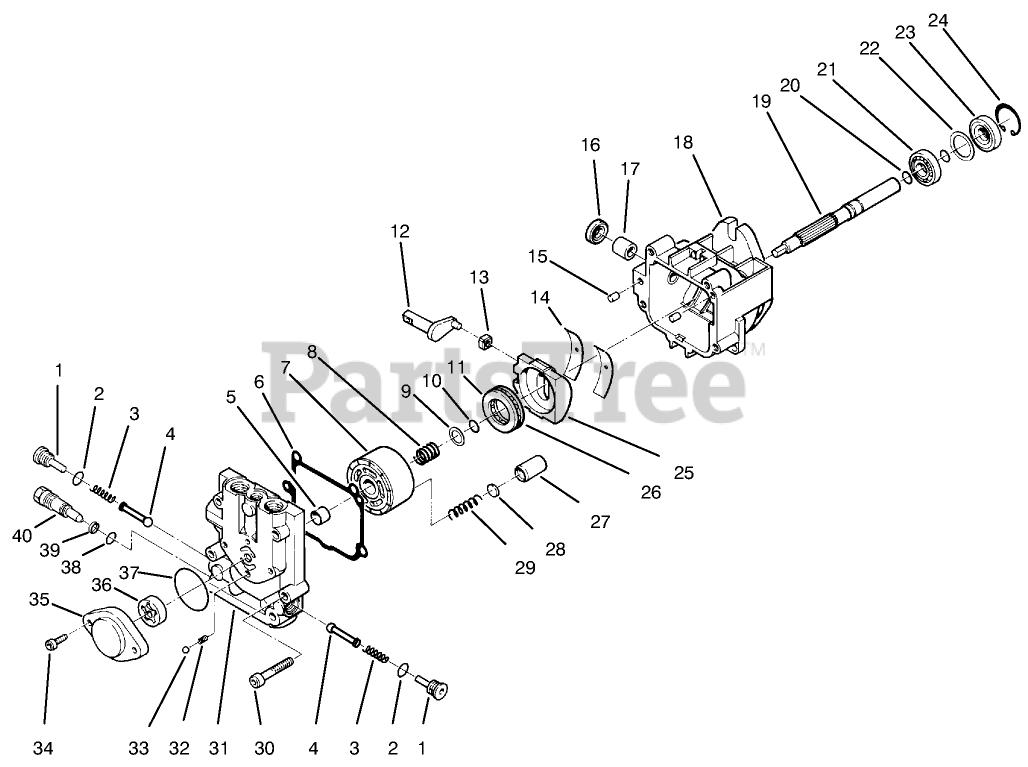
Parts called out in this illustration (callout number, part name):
1	Check Valve Kit (Incl. Ref. #2-4)
2	Seal- O-Ring
4	Poppet
5	Journal- Bearing
6	Gasket- End Cap
9	Washer
10	Ring - Retaining
11	Plate - Thrust
12	Arm - Trunnion
13	Guide - Slot
14	Cradle - Bearing
16	Seal-Lip
17	Journal - Bearing
19	Shaft
20	Ring - Retaining
21	Bearing - Ball
23	Seal- Lip
24	Ring - Retaining
25	Swashplate Assembly
26	Roller - Thrust
28	Washer - Thrust
29	Spring - Piston
32	Ball
35	Housing - Charge Pump
36	Gerotor Assembly
37	Seal- O-Ring
38	Seal- O-Ring
39	Ring-Back Up
40	Valve - Bypass
